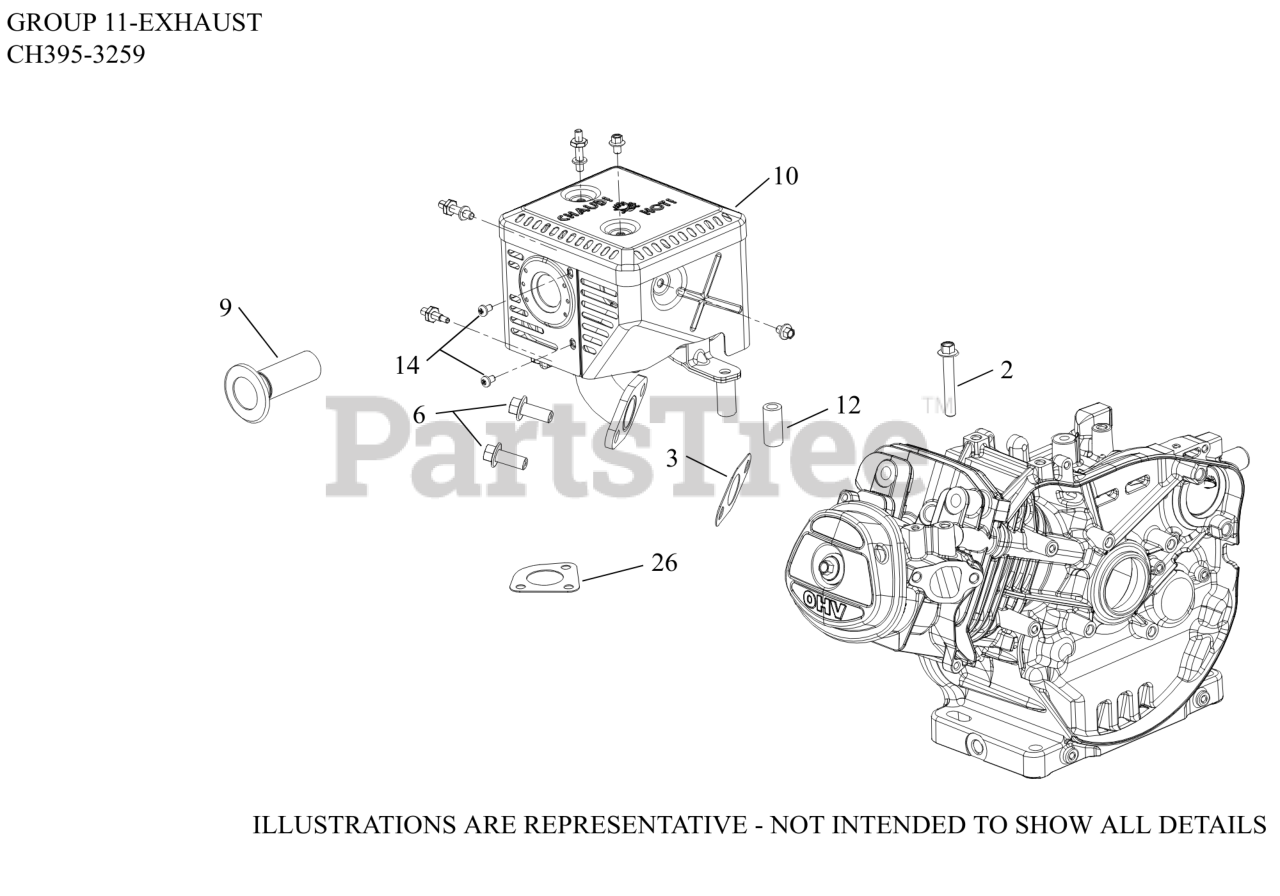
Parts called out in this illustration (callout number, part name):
2	SCREW, M8 X 55
3	GASKET, MUFFLER
6	SCREW, M10 X 25
9	ARRESTOR ASSEMBLY, SPARK
10	MUFFLER ASSEMBLY W/HEAT SHIELD
12	POST, MUFFLER BRACKET
14	SCREW, M5 X 8
26	GASKET, MUFFLER
